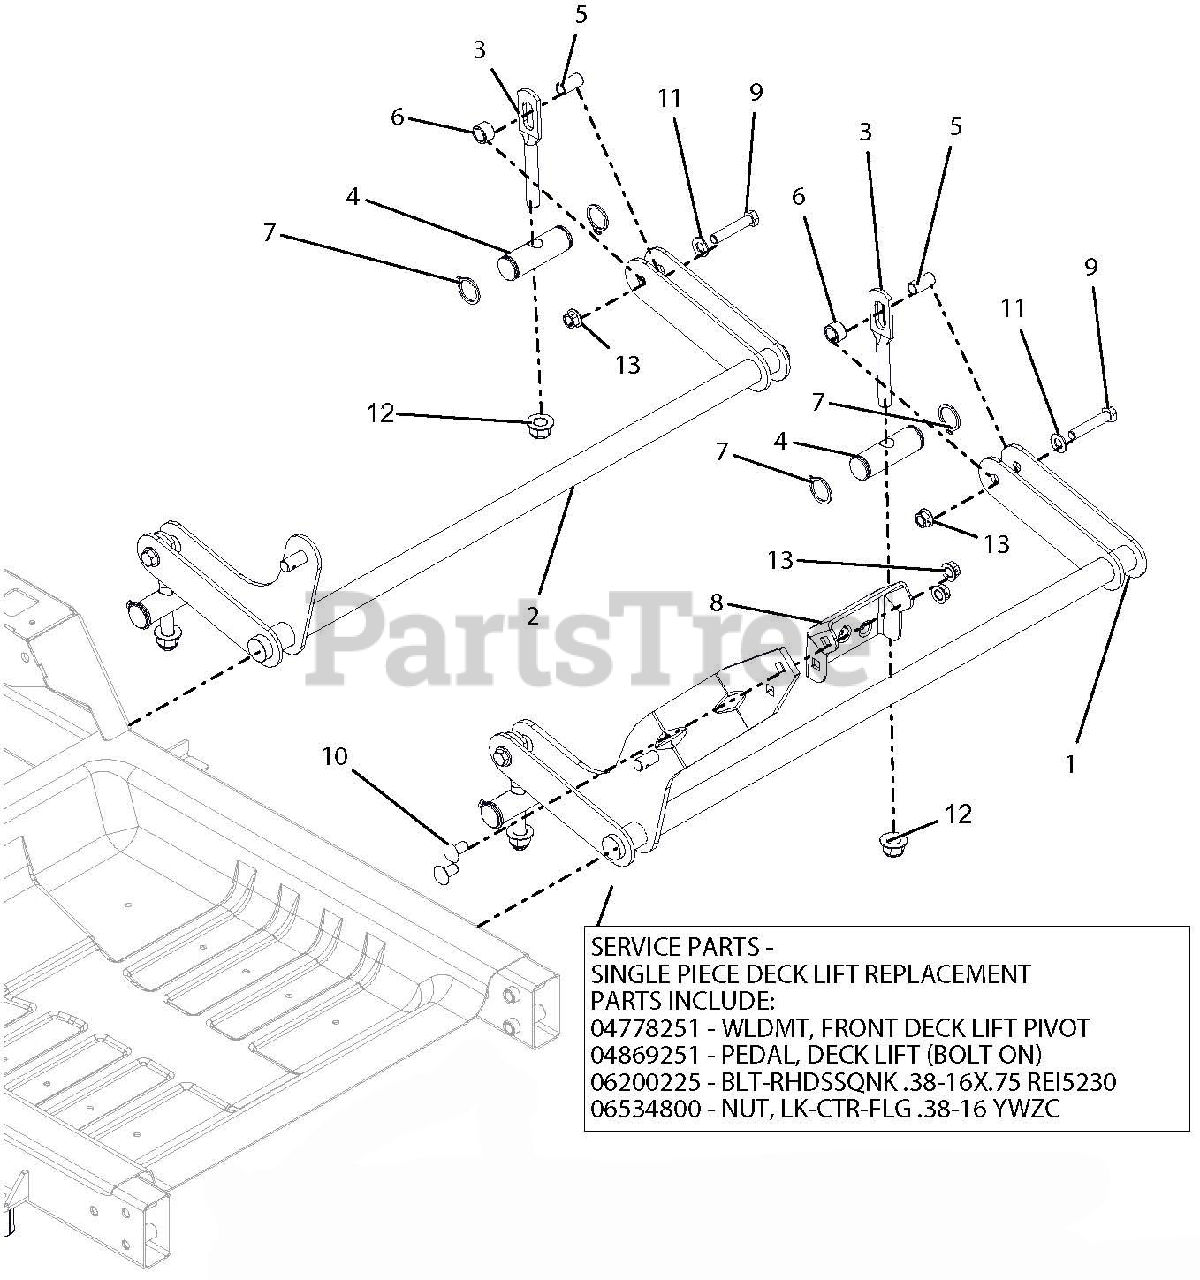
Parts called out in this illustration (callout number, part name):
1	WLDMT, FRONT DECK PIVOT
2	WLDMT, REAR DECK PIVOT
3	LINK, DECK
4	SHAFT, DECK LINK PIVOT
5	BSHG-SLV .385X.500X1.045
6	BSHG-SLV .510X.751X.475
7	RG-RTNG-EXT 1.00X.078
8	PEDAL, DECK LIFT (BOLT ON)
9	BLT-HEX .38-16X2.00 GR8 YWZC
10	BLT,RHSN .38-16X.75 G5 BFP
11	@WSHR-FL-STL.406X.812X.065 YWZ
12	@NUT-LK-NYL-FLG .50-13 YWZC
13	NUT-LK-CTR-FLG .38-16 YWZC
